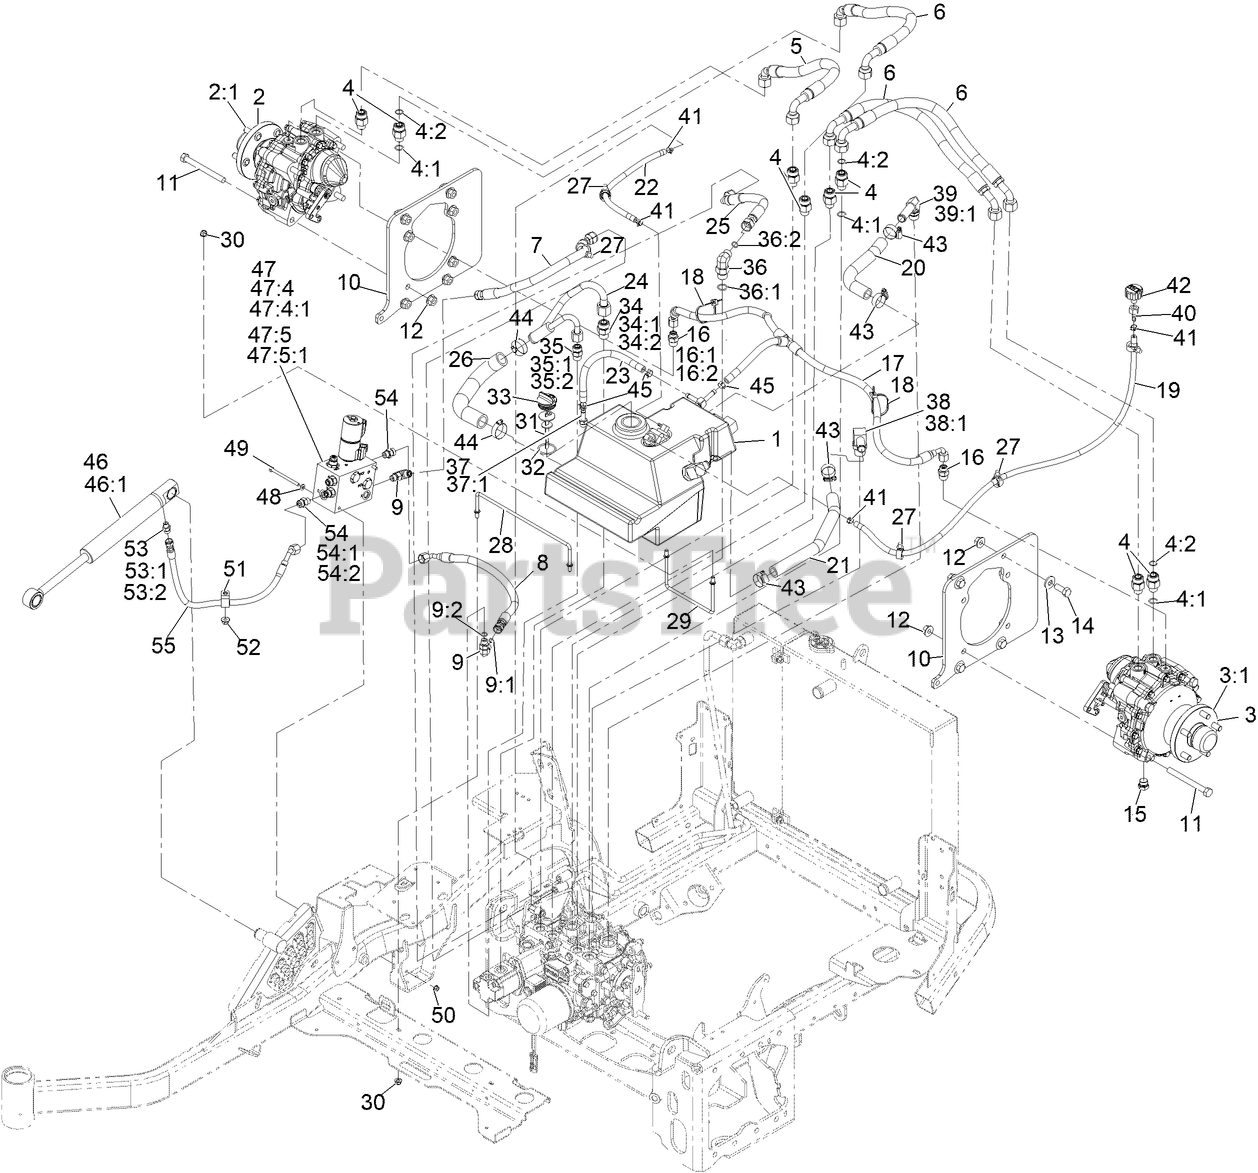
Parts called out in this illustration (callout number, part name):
1	HYD RESERVOIR ASM
2	MOTOR-HYD, RH
2:1	5 STUD WHEEL HUB KIT
3	MOTOR-HYD, LH
3:1	5 STUD WHEEL HUB KIT
4	FITTING-STRAIGHT
4:1	O-RING
4:2	O-RING
5	HOSE ASM
6	HOSE ASM
7	HOSE ASM
8	HOSE ASM
9	FITTING-ELBOW, 90 DEG
9:1	O-RING
9:2	O-RING
10	PLATE-MOTOR
11	SCREW-HH
12	NUT-HHF
13	WASHER-SPRING
14	SCREW-HH
15	PLUG-MAGNETIC
16	FITTING-STRAIGHT
16:1	O-RING
16:2	O-RING
17	TEE HOSE ASM
18	TIE-CABLE
20	HOSE-RETURN
21	HOSE-RETURN
24	TUBE ASM
25	HOSE ASM
26	HOSE-SUCTION
27	CLIP-TIE
28	ROD-SUPPORT, HYD TANK
29	ROD-SUPPORT, HYD TANK
30	NUT-HF, NI
31	DIPSTICK
32	O-RING
33	PLUG-PLASTIC
34	FITTING-STRAIGHT
34:1	O-RING
34:2	O-RING
35	FITTING-STRAIGHT
35:1	O-RING
35:2	O-RING
36	FITTING-ELBOW, 90 DEG
36:1	O-RING
36:2	O-RING
37	ADAPTER-STRAIGHT
37:1	O-RING
38	FITTING-ELBOW, 90
38:1	O-RING
39	FITTING-90
39:1	O-RING
40	FITTING-STRAIGHT
41	CLAMP-HOSE
42	BREATHER
43	CLAMP-HOSE
44	CLAMP-HOSE
45	CLAMP-HOSE
46	CYLINDER-LIFT
46:1	KIT, CYL REPAIR
47	VALVE-LIFT AND HOLD
47:4	SOLENOID VALVE ASM
47:4:1	SPOOL VALVE SEAL KIT
47:5	VALVE-COUNTERBALANCE
47:5:1	SEAL KIT
48	WASHER-FLAT
49	SCREW-HH
50	NUT-HF
51	CLIP-LOOM
52	NUT-HF, NI
53	FITTING-HYD, STRAIGHT
53:1	O-RING
53:2	O-RING
54	FITTING-STRAIGHT
54:1	O-RING
54:2	O-RING
55	HOSE ASM
